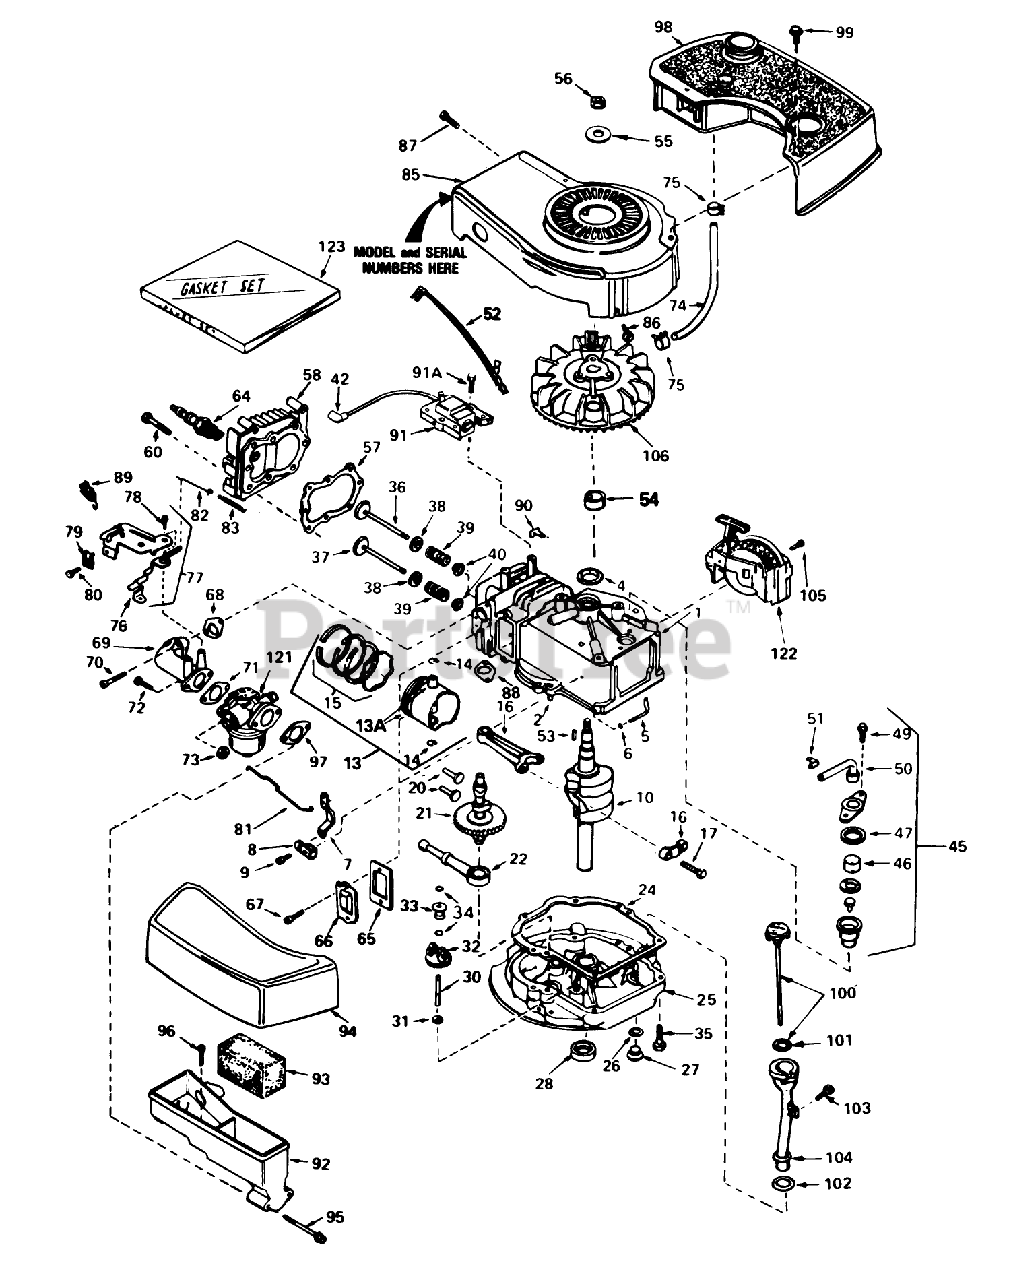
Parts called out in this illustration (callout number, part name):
1	Cyiinder Assy. (Incl. Ref. #2, 4 105)
2	Pin-Dowel
4	Seal-Oil
5	Rod, Governor (Incl. No. 36)
6	Washer-Flat
7	Governor Lever
8	Clamp-Lever, Governor
9	Screw
10	Crankshaft
13	Piston, Pin Ring Assy. (Std.) (Incl. Ref. #13A, 14 15)
13	Piston, Pin Ring Assy. (.010 oversize) (Incl. Ref. #13A, 14 15)
13	Piston, Pin Ring Assy. (.020 oversize) (Incl. Ref. #13A, 14 15)
13A	Piston Pin Assy. (Incl . Ref. . #14) (Std.)
13A	Piston Pin Assy. (Incl. Ref. #14) (.010 Oversize)
13A	Piston Pin Assy. (.020 oversize) (Incl. Ref. #14)
14	Ring-Retaining, Piston Pin
15	Ring Set (Std.)
15	Ring Set (.020" OS)
15	Ring Set (.010" OS)
16	Rod Assy., Connecting (Incl. Ref. #17)
17	Bolt-Rod, Connecting
20	Lifter-Valve
21	Camshaft(Mech.Comp. Release)
22	Oil Pump ASM
24	Gasket, Mounting
25	Flange Assy., Mounting (Incl. Ref. #26thru 30)
26	Gasket-Oil Drain
27	Plug Oil Drain
28	Seal Oil
30	Shaft-Governor
31	Washer-Flat
32	Governor Gear ASM
33	Spool-Governor
34	Ring-Retaining
35	Screw (1/4-20 x 1-1/4)
36	Valve, Intake (Std.) (Incl. Ref. #40)
36	Valve, Intake (1/32" oversize)(Incl. No. 40)
37	Valve, Exhaust (Std.)(Incl. No. 40)
37	Valve, Intake (1/32" oversize)(Incl. No. 40)
38	Cap-Upper Valve Spring
39	Spring-Valve
40	Cap-Valve, Spring
42	Cover-Spark Plug
45	Breather Assy. (Incl. Ref. #46 thru 51)
46	Element-Breather
47	Gasket-Breather
49	Screw (10-24 x 9/16)
50	Tube, Breaker
51	Clip, Breather
52	Wire-Ground
53	Key-Flywheel
54	Spacer
55	Washer-Belleville
56	Nut-Flywheel
57	63573 GIL 42 SNWTHW
58	Head-Cylinder
60	Screw (5/16-18x1-1/2)
64	Plug, Spark (J17LM or equiv.)
64	Plug, Spark (Champion RCJ-8)
65	Gasket-Breather
66	Cover-Valve
67	Screw
68	Gasket-Intake
69	Pipe, Intake (Incl. No. 68)
70	Screw (1/4-20 x 1)
71	Gasket-Carburetor
73	Nut and Lock Washer (1/4-28)
74	Line-Fuel
75	Clamp-Line, Fuel
76	Lever Control
77	Control Assy., Speed (Incl. Nos, 76, 78 89)
78	Screw, Hex Washer Hd Shoulder Self-Tap
79	Conduit
80	Screw (10-32 x 3/8)
81	Link-Throttle
82	Link Governor Spring
83	Spring Governor
85	Housing-Blower
86	Screw (1/4-20x19/32)
87	Screw (10-24 x 9/16)
88	Gasket Exhaust
89	Terminal
90	Clip-Wire
91	Solid State
91A	Screw
92	Body Air Cleaner
93	Filer, Air
94	Cove, Air Cleaner
95	Screw Fil Hd.
96	Screw, Hex Hd.
97	Gasket-Air Cleaner
98	Tank-Fuel
99	Screw (10-32 x 35/64)
100	Dipstick, Oil (Incl. Ref. #101)(Twist Lock)
101	O-Ring
102	Gasket
103	Screw (10-32 x 1/2)
104	Tube-Oil Fill
105	Screw (1/2-20x5/8)
106	Flywheel
121	Carburetor (Incl. Ref. #71)
122	Starter-Sidemount
123	Gasket Set
